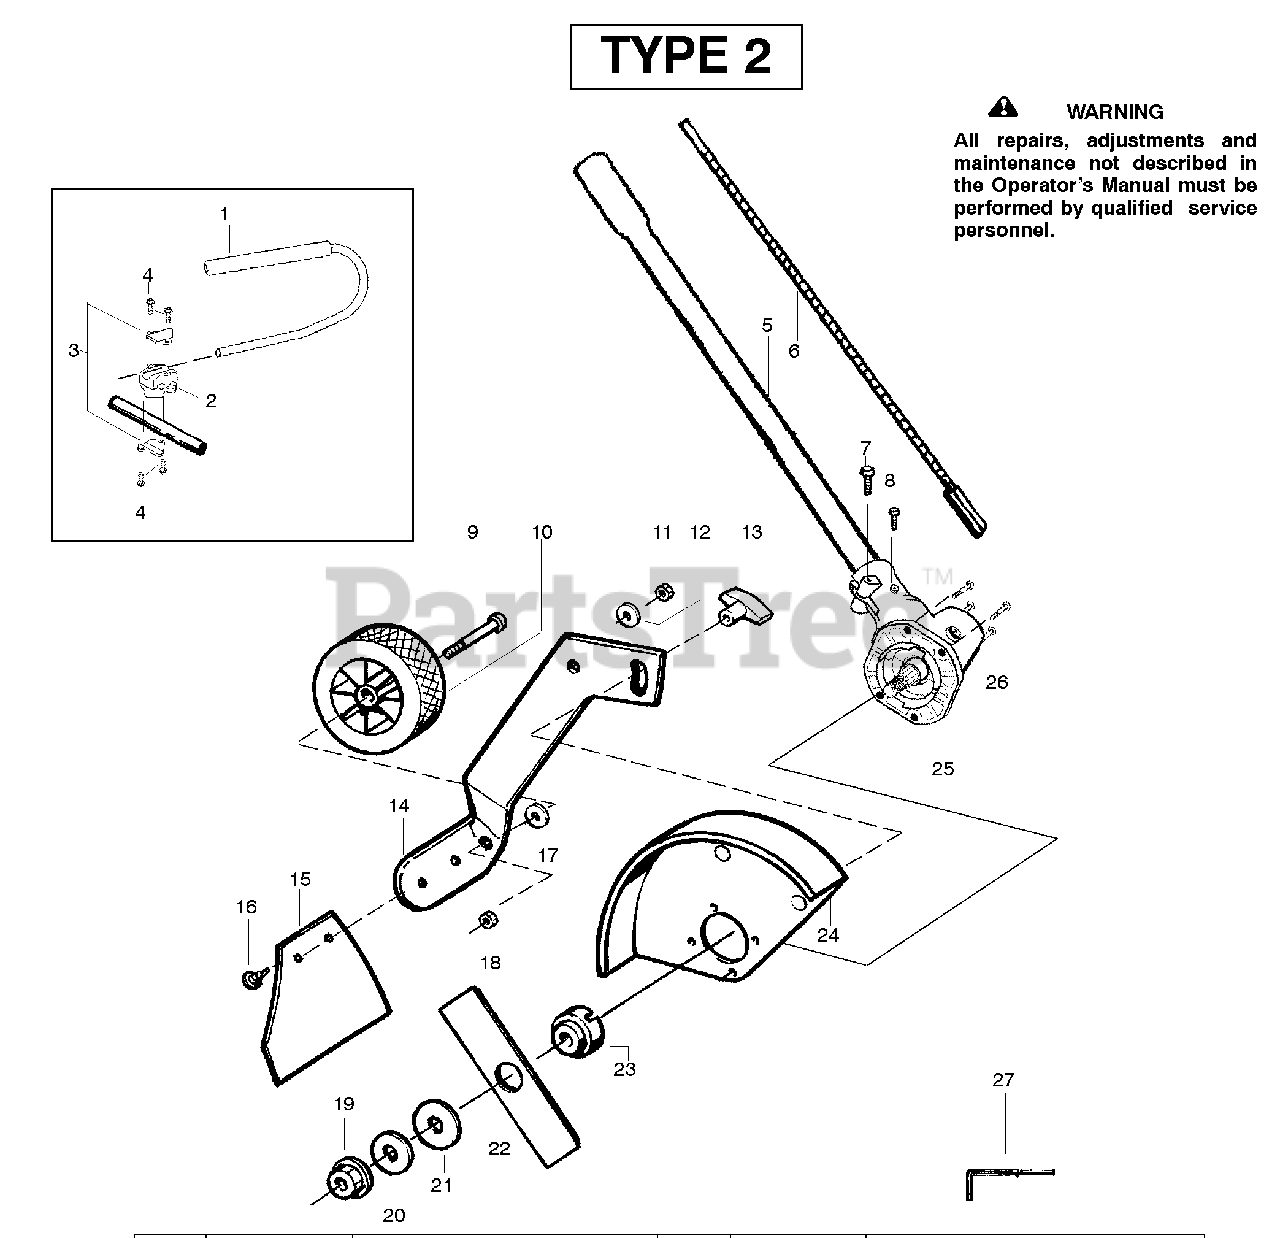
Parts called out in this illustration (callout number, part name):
1	Kit-Handlebar
2	Clamp-Handlebar ( 7/8" )
2	Clamp-Handlebar ( 1" )
3	Bracket-Clamp
5	Assy.-Driveshaft
6	Flexshaft-Split boom
8	Screw-Alignment
9	Bolt-Shoulder Axle
10	Wheel-4" (rubber)
14	Bracket-Adj. Wheel
15	Kit-Mud Flap
16	Fastener-Mud Flap
19	Nut-Flange (L.H.)
20	Washer-Belleville
22	Accy-7.5" Blade
24	Kit-Edger Guard
27	Wrench-Hex ( 5/32")
